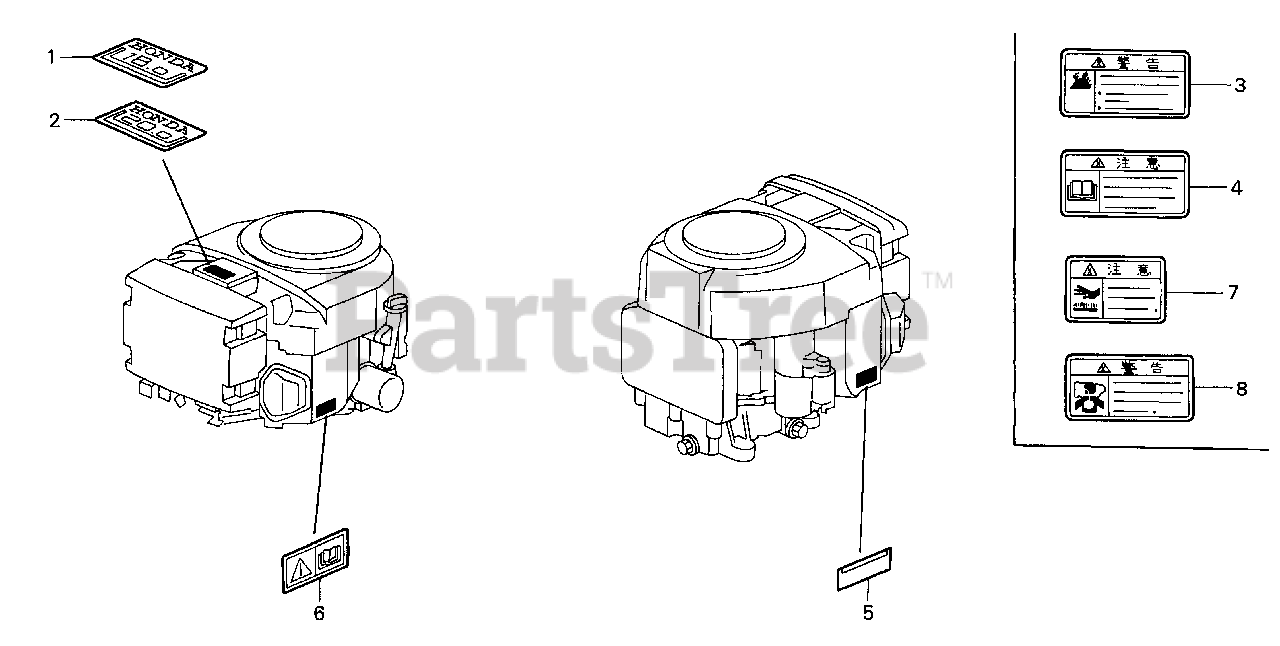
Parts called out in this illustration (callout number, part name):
1	MARK, EMBLEM
3	MARK, FUEL WARNING
4	MARK, CAUTION (J)
5	LABEL, SPECIFICATION (GXV610)
7	MARK, HEAT CAUTION
8	MARK, EX. GAS WARNING
